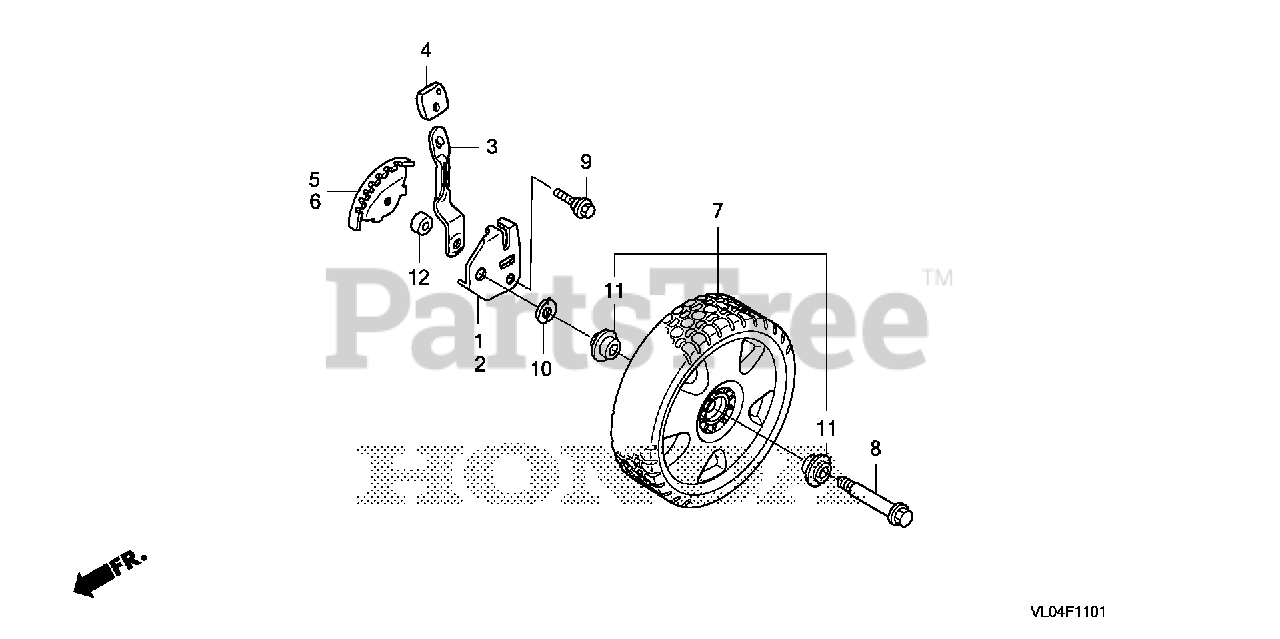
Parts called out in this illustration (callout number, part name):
1	ARM, R. FR. ADJUSTING
2	ARM, L. FR. ADJUSTING
3	PLATE, FR. ADJUSTER
4	GRIP, ADJUSTER *NH164* (GRIP GRAY)
5	PANEL, R. FR. ADJUSTING
6	PANEL, L. FR. ADJUSTING
7	WHEEL, FR. *NH164* (GRIP GRAY)
8	BOLT, FR. WHEEL SHAFT
9	BOLT, ADJUSTER ARM
10	WASHER, WHEEL
11	BEARING, RADIAL BALL
11	BEARING, WHEEL
12	COLLAR, FR. ADJUSTING
